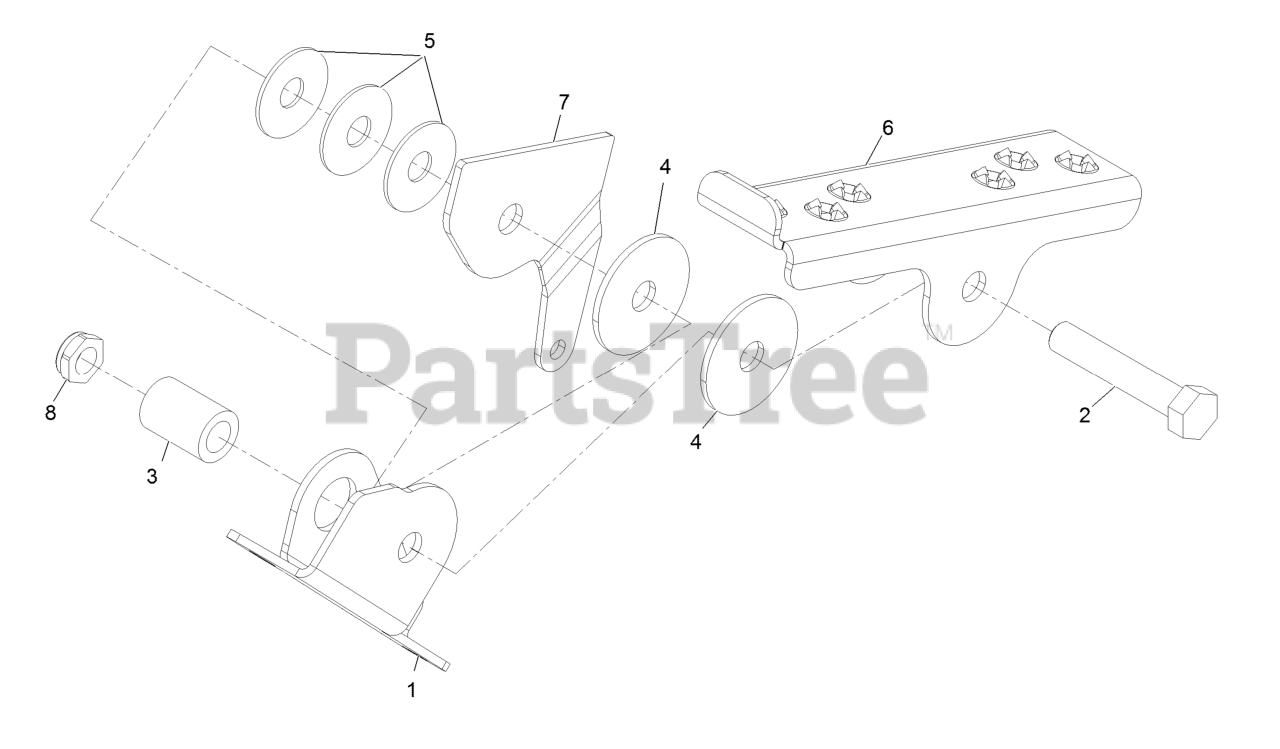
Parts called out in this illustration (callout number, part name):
1	Bracket-Pedal Mount
2	Screw-HH 1/2-13 X 2 3/4
3	Spacer-Roller
4	Disc-Friction
5	Washer-Spring Disc
6	Channel,Pedal Link
7	Arm, Foot Pedal
8	Nut-Nyloc 1/2-13 Thin
